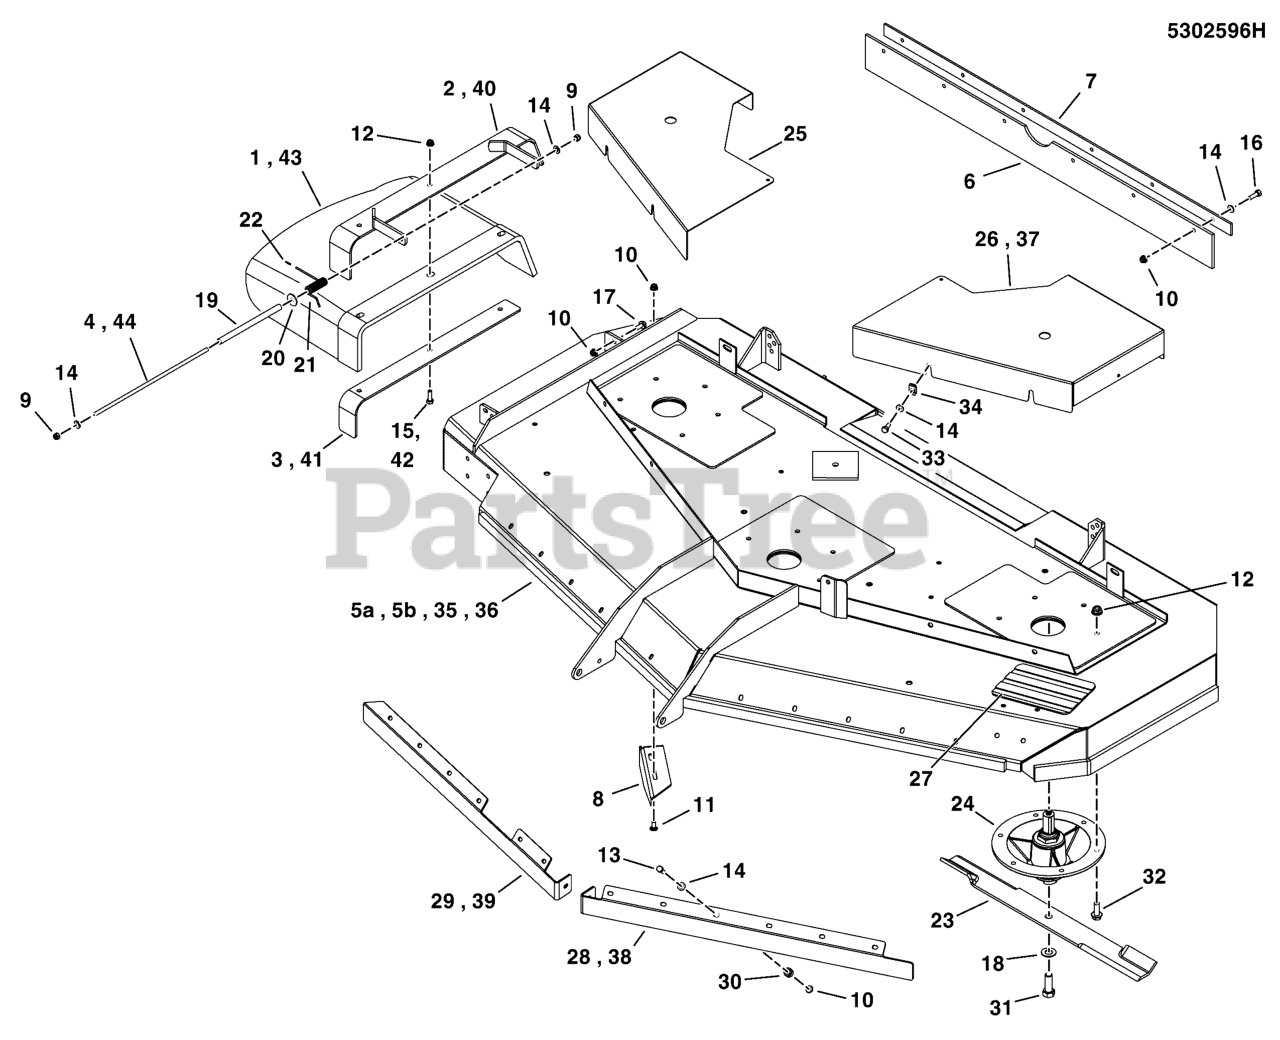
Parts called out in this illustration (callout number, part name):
1	CHUTE, DISCHARGE, RUBBER, 61/72, BENT
2	WELD, FRAME, CHUTE, 72 - BLK
3	SUPPORT, DISCHARGE CHUTE, 61/72 - BLK
4	ROD, MOUNT, CHUTE, 72, CZ
5A	* DECK SHELL W/ DECALS, 5100/72
5B	* DECK SHELL W/ DECALS, 5100/72 CE
6	FLAP, STRIPER, 72 DECK
7	PLATE, SUPPORT, 72" - BLK
8	PLATE, DEFLECTOR, 72 - BLK
9	NUT, 5/16-24 HEX NYLON LOCK
10	NUT, 5/16-18 HEX NYLOCK FLANGE NUT
11	BOLT, 5/16-18 X 3/4, CARRIAGE, GD5, CZ
12	NUT, 3/8 - 16 HEX NYLOCK FLANGE
13	BOLT, 5/16-18 X 1-1/4" GD5 YZ
14	WASHER, 5/16" SAE
15	BOLT, 3/8-16 X 1-1/4" GD5 CZ
16	BOLT, 5/16-18 X 1" GRD5 YZ
17	BOLT, 5/16-18 X 3/4 GD5
18	WASHER, BLADE BOLT, 9/16" F436, CZ
19	TUBE, 1/2 X 3/8 X 12.50 BLACK POLY
20	WASHER, 5/16" Fender
21	SPRING, TORSION
22	CAP, PROTECTOR, .120 ID
23	BLADE, 25 X 25 X 2.50, HIGH LIFT (SET OF 3)
24	SPINDLE ASSEMBLY
25	GUARD, DECK - RH - RED
26	GUARD, DECK - LH - RED
28	BAFFLE, BLOWOUT, IS5100Z CE, LH - RED
29	BAFFLE, BLOWOUT, IS5100Z CE, RH - RED
30	SPACER, .39 X .75 X .50, CZ
31	BOLT, 5/8-11 X 1-3/4 GD8
32	BOLT, 3/8-16 X 1-1/4, FLANGE, GD 5, CZ
33	BOLT, 5/16-18 X 3/4 GD5
34	BODY CLIP, 5/16-18-7GA MATERIAL
35	* DECK SHELL W/ DECALS, 72, 5100, DOM
36	* DECK SHELL W/ DECALS, 72, 5100, CE
37	GUARD, 72" LH - RED
38	PLATE, BLOWOUT BAFFLE IS5100Z CE, LH - RED
39	PLATE, BLOWOUT BAFFLE IS5100Z CE, RH - RED
40	MOUNT
41	SUPPORT, DISCHARGE CHUTE - BLK
42	BOLT, 3/8-16 X 1-1/2, CARRIAGE, GD5, CZ
43	CHUTE, RUBBER DISCHARGE (5104442)
44	ROD, MOUNT, CHUTE, 61, CZ
